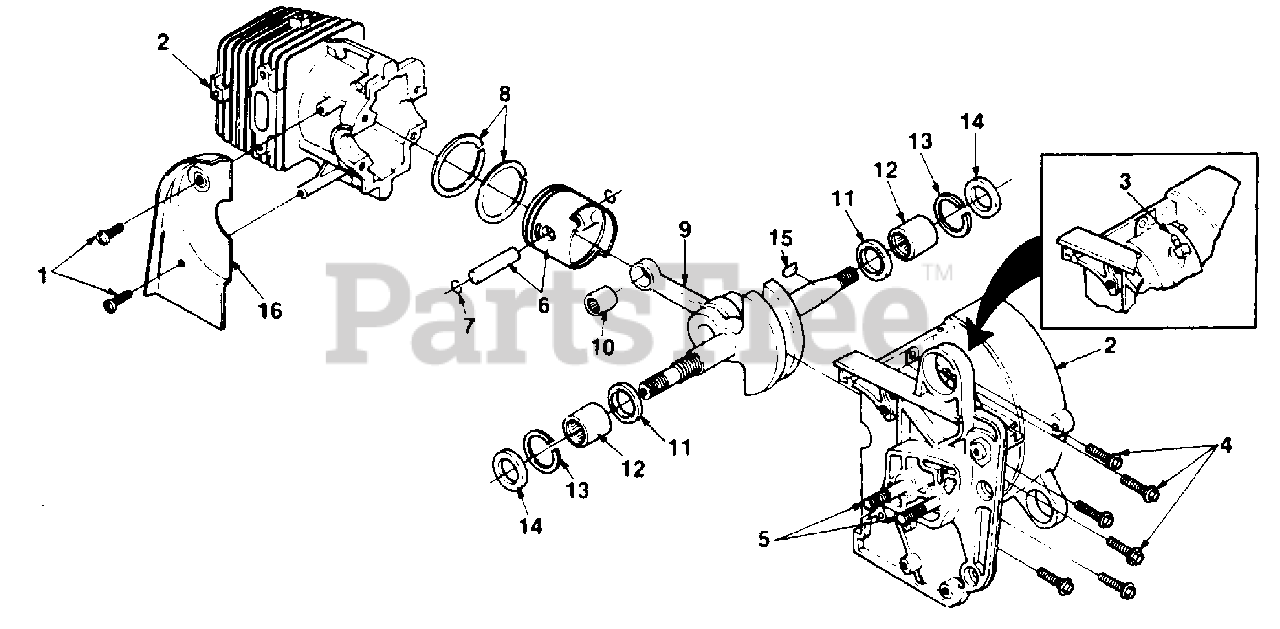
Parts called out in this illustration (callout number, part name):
1	SCREW- Sems hex (10-24 x 1/2)
2	CRANKCASE & CYLINDER
3	FITTING- Tube
4	SCREW- (10-24 x 1)
5	BOLT- Guide bar
7	RING- Retaining
8	PISTON RING
9	CRANKSHAFT
10	BEARING- Rod
11	WASHER- Thrust
12	BEARING- Needle
13	RING- Retaining
14	SEAL- Crankshaft
15	KEY- Woodruff
16	SHIELD- Sawdust
